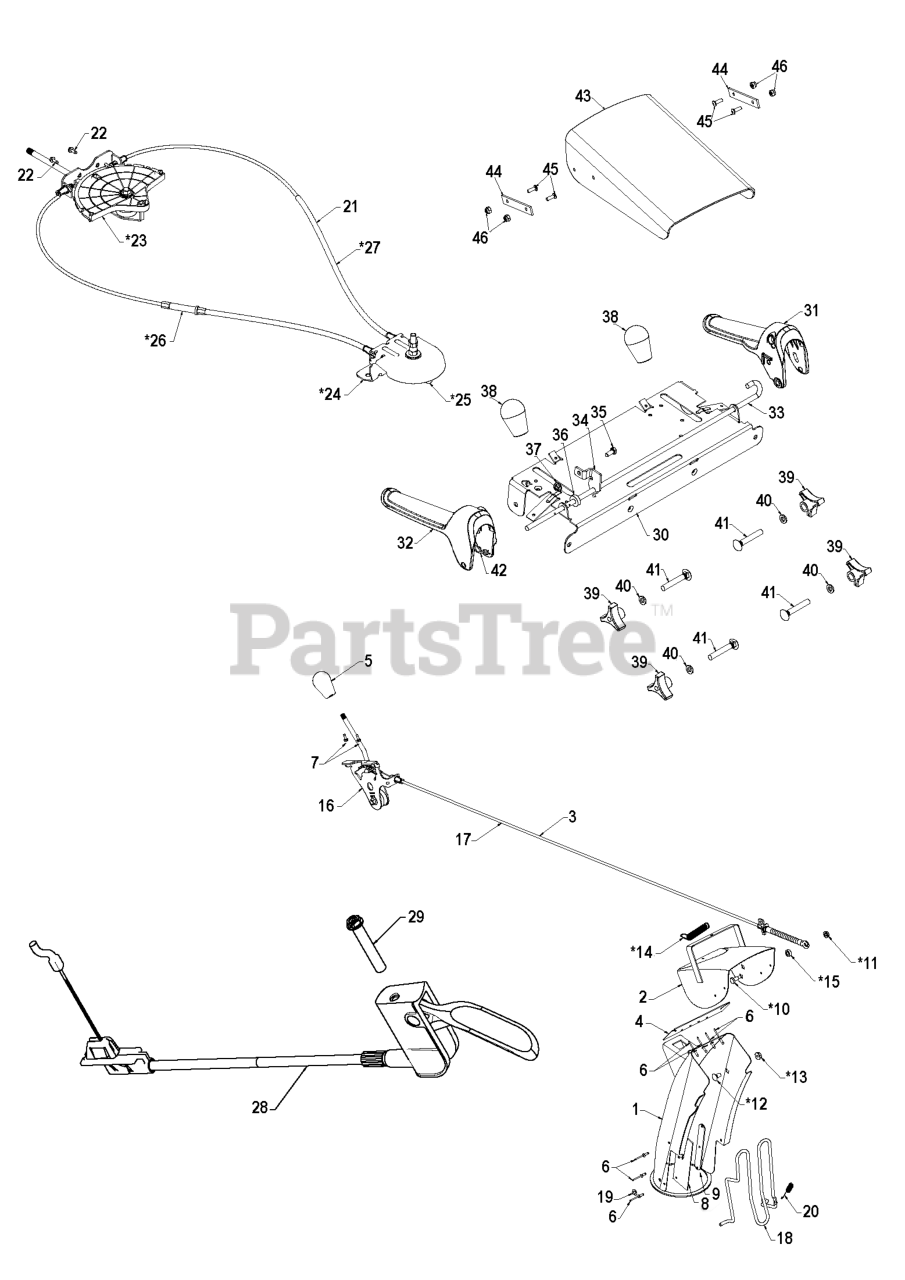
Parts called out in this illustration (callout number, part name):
1	ASM.CHUTE/DEFLECTOR.668
3	CONTROL.ASM.DEFLEC.BLK.BOWDEN
5	KNOB.OVERMOLD.DS.HUSQVARNA/BLK
16	RP CNTRL.HEAD.ASSEM.DEFLECTOR
17	RP CABLE.DEFLECTOR.CONTRL.BOWD
18	ROD.GUARD.CHUTE (2 2)
19	NUT
20	SPRING.CHUTE.GUARD
21	LEVER/CABLE.ASM.ROTATOR
28	CABLE.ASM.HYDROII.BLK/BLK
30	PANEL.CONTROL.SNOW.BLACK
31	LEVER.CONTROL.LH.PL.BLACK
32	LEVER.CONTROL.RH.PL.BLACK
33	BAIL.CONTROL.INTERLOCK.SNOW
34	BRACKET.ARM.IMPELLER.ROD.YZ
35	BOLT
36	SPACER.CONTROL.LEVER
38	KNOB.OVERMOLD.DS.HUSQVARNA/BLK
39	KNOB.HANDLE.3/8.TRI-POINT.BLAC
40	WASHER
41	BOLT 3/8-16 X 2-1/4
42	SPRING RETAINER
43	SHIELD.DEFLECTOR.BLACK.SNOW
44	DEFLECTOR SHIELD STRAP
45	SCREW.MACHINE.8-32 X 1/2-BLK
46	NUT.HEX.NYLOCK
